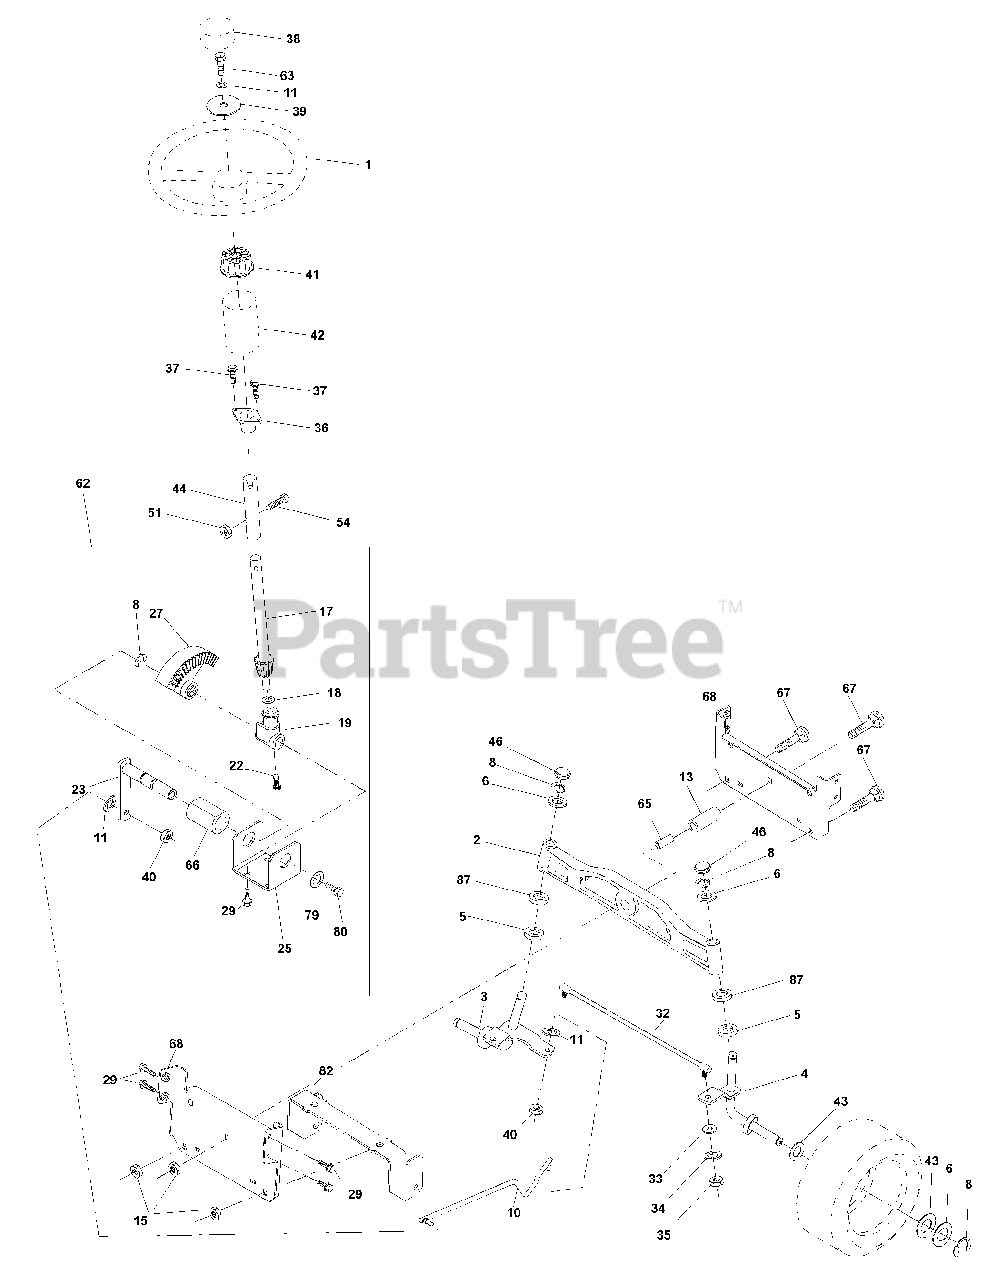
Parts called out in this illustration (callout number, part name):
1	Wheel Steering
2	Axle Asm Cast Iron LT
3	Spindle Asm LH
4	Spindle Asm RH
5	Bearing Race Thrust Harden
6	Washer 25/32 X 1-5/8 X 16 Ga
8	Ring Klip #t5304-75
10	Link Drag
11	Washer Lock Hvy Hlcl Spr 3/8
13	Spacer Brg Axle Front
15	Nut Hex Flange Lock
17	Shaft Asm Strg
18	Washer Thrust 515 x 750 x 033
19	Support Shaft
22	Screw Hex Wsh Hd Torx
23	Shaft Asm Pittman
25	Bracket Steering
27	Gear Sector
29	Screw 3/8-16 x .75
32	Rod Tie
33	Washer 11/32 x 3/4 x 16 Ga
34	Washer Lock Hvy Hlcl Spr 5/16
35	Crownlock Nut 5/16-24 Unf
36	Bushing Strg
37	Screw
38	Insert Cap Strg Wh
39	Washer 13/32 X 1-1/2 X 11 Ga
40	Lock nut
41	Adaptor Wheel Strg
42	Boot Steering Dash
43	Washer 25/32 X 1 1/4 X 16 Ga
44	Extension Steering Shaft LR/LT
46	Cap Spindle Fr Top Blk
51	Nut Lock Hex w/Ins 5/16-18
54	Bolt Fin Hex 5/16-18 Unc x 1-1/4
62	Kit, Steering Assembly Svc
63	Bolt Fin Hex 3/8-16unc x 1 Gr. 5
65	Spacer Brace Axle
66	Bearing Arm Pittman
67	Bolt Rdhd Sq 3/8-16 Unc x 2-3/4
68	Axle, Brace
79	Washer 13/32 x 1-1/4 x 12 Ga.
80	Bolt Hex Nylon 3/8-16 x 3/4
82	Bracket Susp Chassis Front
87	Washer Flat .781 x 1 1/2 x .14
